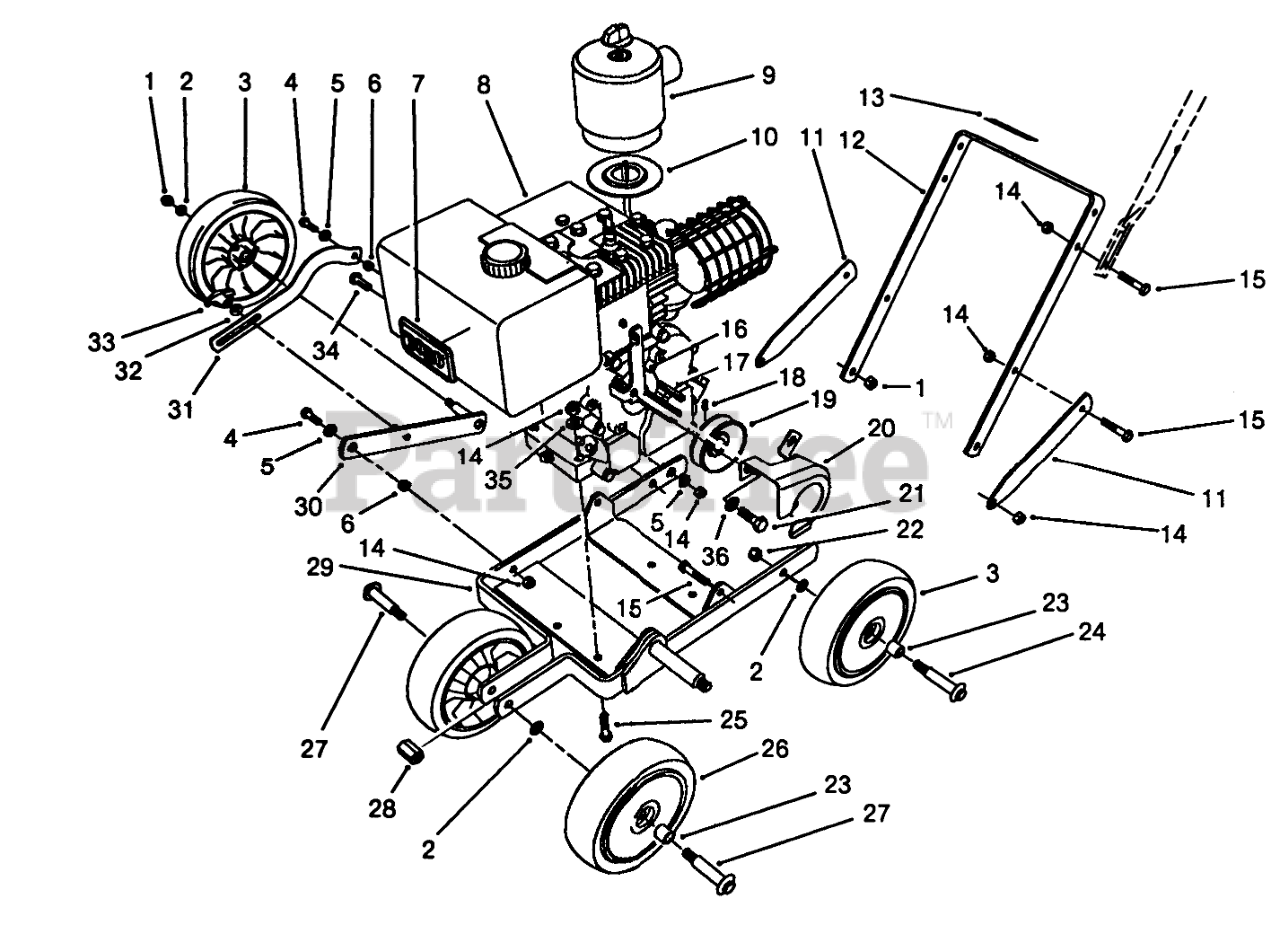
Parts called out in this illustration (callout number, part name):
1	NUT-LOCK
2	WASHER
3	Wheel & Tire Assembly (Incl. Ref. #23)
4	SCREW-HH
5	WASHER-FLAT
6	WHEEL MT BUSHING
7	TORO LOGO PLT
8	Engine-3 hp.
9	AIR CLEANER COVER WA
10	AIR CLEANER BASE
11	SUPPORT HANDLE
12	LOWER HANDLE
13	Decal-Warning
14	NUT-LOCK, NI
15	SCREW-HH
16	SPRING BRACKET
18	SCREW-SET
19	PULLEY (3.5 HP)
20	ENG. PULLEY GUARD
21	SCREW-HH
22	NUT-HEX
23	BUSHING
24	WHEEL BOLT
25	SCREW-HH
26	Wheel & Tire Assembly (Incl. Ref. #23)
27	BOLT-WHEEL
28	HEX SPACER
29	Frame-Edger
30	WHEEL MOUNT WA
31	AXLE LINK
32	BELLEVILLE SPRING WASHE
34	3/8-24 X 1.00HEX BU. HD
35	WASHER-PLAIN
36	WASHER-LOCK
